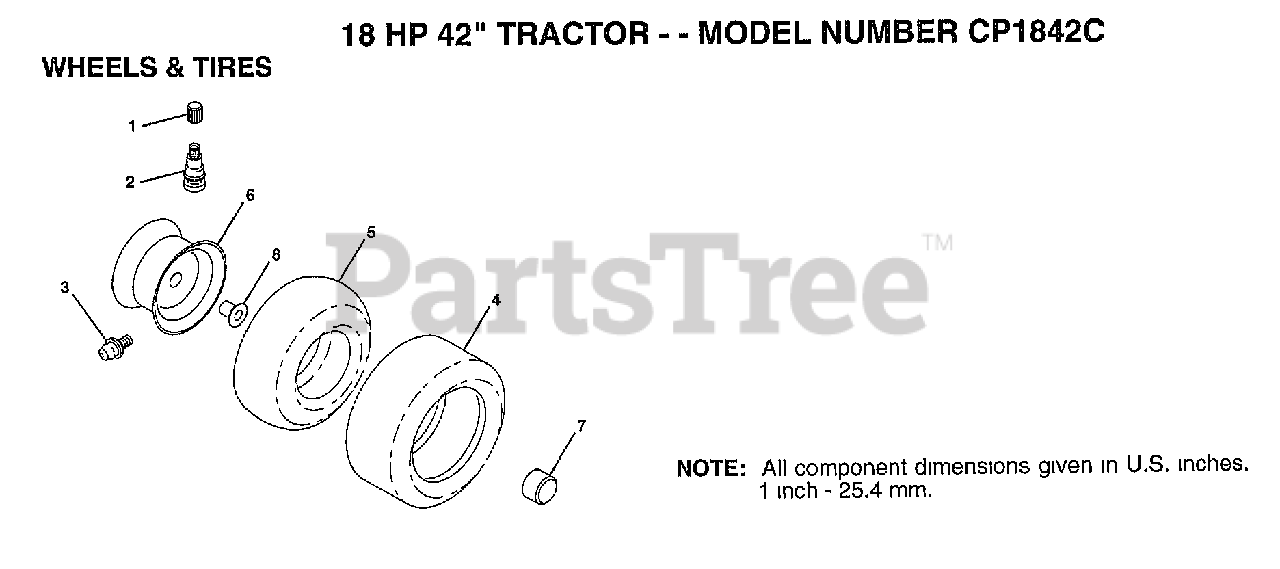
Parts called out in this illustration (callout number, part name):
1	VALVE CAP
2	VALVE STEM LT
3	FITTING LT
4	TIRE.20X8-8
5	TUBE.5.3/4.5/6
5	TUBE.18X9.5-8
7	HUB CAP
8	"FLANGE, BEARING"
